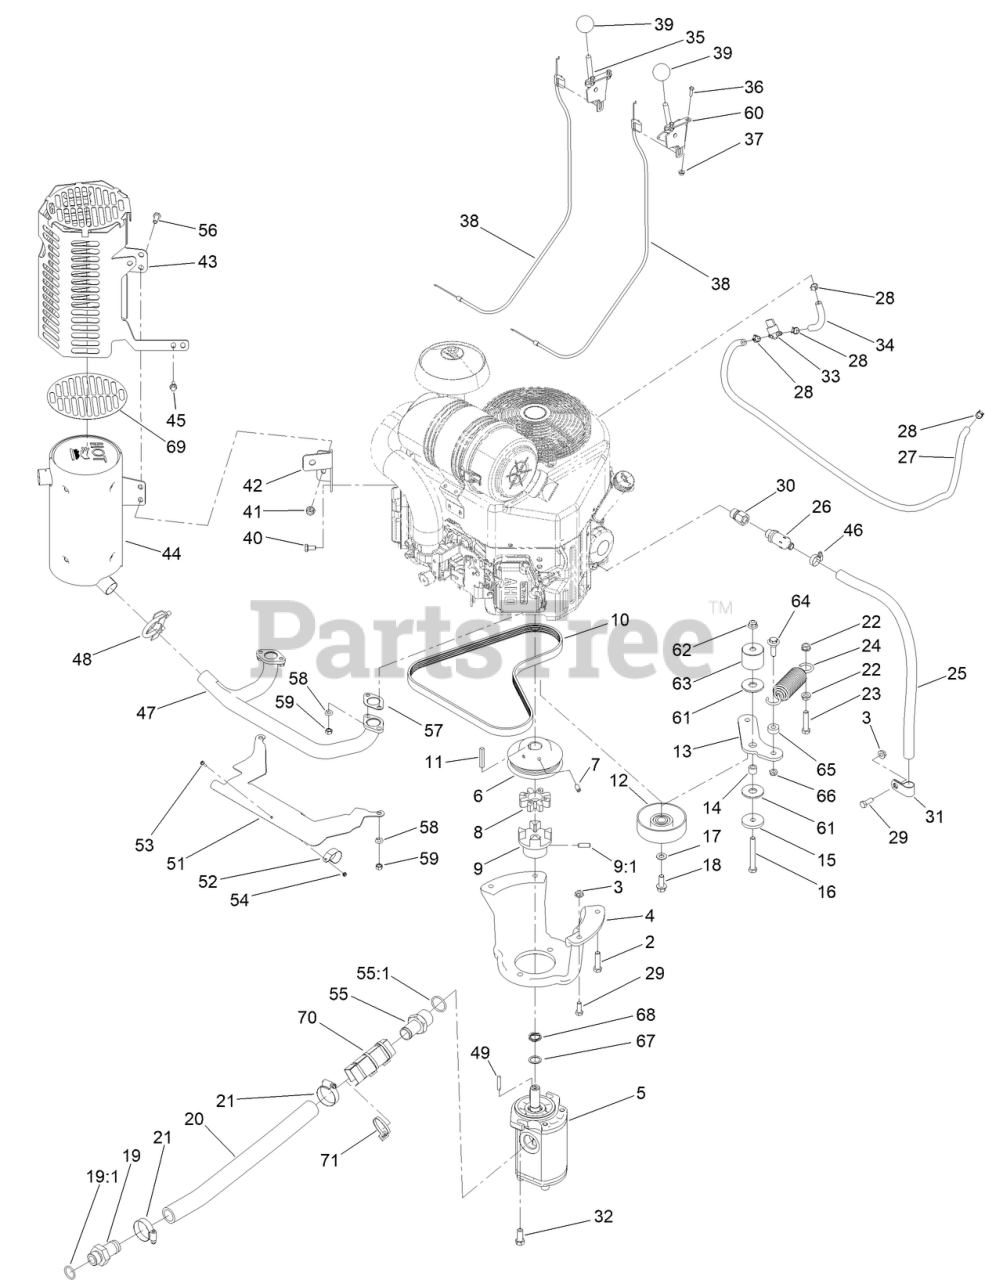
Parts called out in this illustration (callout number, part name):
2	SCREW-HH
3	NUT-HF
4	MOUNT-PUMP
5	GEAR PUMP ASM
6	PULLEY-ENGINE
7	SCREW-SET, HSH
8	COUPLER-SPIDER
9	COUPLER-FLEX
9:1	SCREW-SET, HSH
10	BELT-V
11	KEY-SQUARE
12	PULLEY-IDLER
13	ARM-IDLER
14	BUSHING-LEVER, LIFT
15	WASHER-PLAIN
16	SCREW-HH
17	WASHER-FLAT
18	SCREW-HHF
19	FITTING
19:1	O-RING
20	HOSE-SUCTION
22	NUT-HHF, WHIZ
23	SCREW-HH
24	SPRING-EXTENSION
26	VALVE-DRAIN, OIL
27	HOSE-FUEL
28	CLAMP-HOSE
29	SCREW-HH
30	ADAPTER
31	CLAMP-R
32	SCREW-HH
33	VALVE-FUEL
34	HOSE-FUEL
35	LEVER-CONTROL
37	NUT-LOCK, FLANGE
38	CABLE-CONTROL
40	SCREW-HH
41	NUT-HF
42	BRACKET-MOUNT, MUFFLER
43	GUARD-MUFFLER
44	MUFFLER
45	SCREW-HHF
46	CLAMP-HOSE
47	MANIFOLD, MUFFLER
48	CLAMP-MUFFLER
49	KEY-SQUARE
51	PLATE-SHIELD, HEAT
53	SCREW-PAN
54	NUT-HEX
55	FITTING-STR
55:1	O-RING
56	SCREW-HH
57	GASKET-EXHAUST
58	WASHER-SPRING
59	NUT-HEX
60	LEVER-CONTROL
61	WASHER-FRICTION, COMPOSITE
62	NUT-HF, NI
63	SPACER-IDLER
64	SCREW-SHOULDER, HWH
65	SPACER
67	WASHER-THRUST
68	WASHER-WAVE
69	FOIL-GUARD
70	PROTECTOR-HOSE
71	TIE-CABLE
